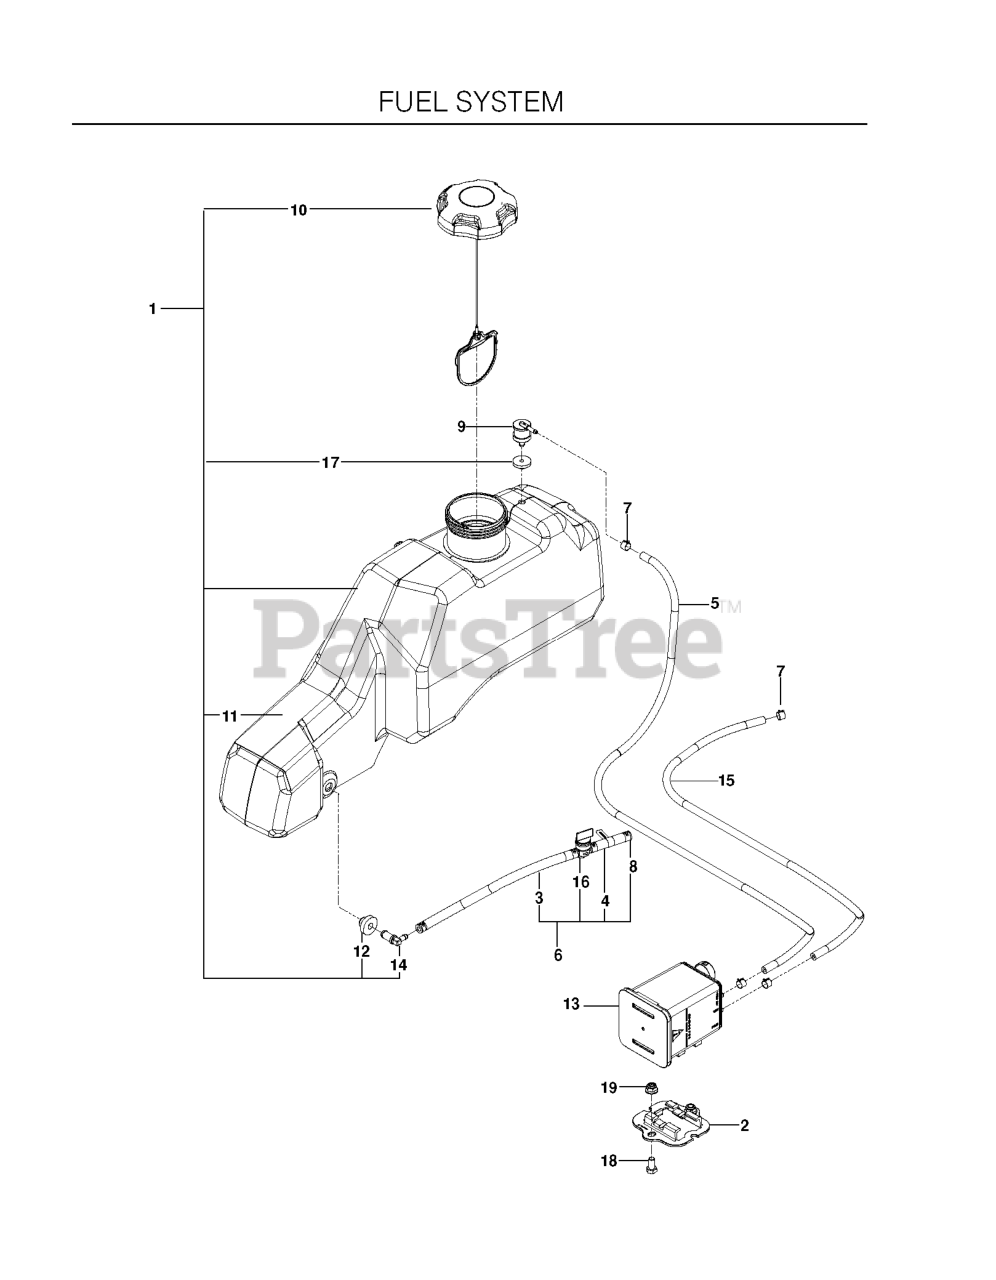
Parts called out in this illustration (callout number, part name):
1	TANK.FUEL.ASSEMBLY.LARGE
2	BRACKET, CANISTER
3	GAS LINE 10"
4	FUEL LINE 3"
5	HOSE, VAPOR 3/16 X 39"
6	FUEL LINE ASSY
7	CLAMP, HOSE
8	HOSE CLAMP
9	VALVE.FUEL.CHECK
10	CAP, FUEL
11	SHIELD, HEAT
12	RUBBER GROMMET
13	CANNISTER, CARBON
14	STEM, FUEL TANK
15	HOSE, FUEL, 3/16" X 20"
16	FUEL VALVE
17	GROMMET, CHECK VALVE
18	HCS 5/16-18 X 5/8 GR 5 ZD
19	5/16-18 NYLOC FLANGE NUT
